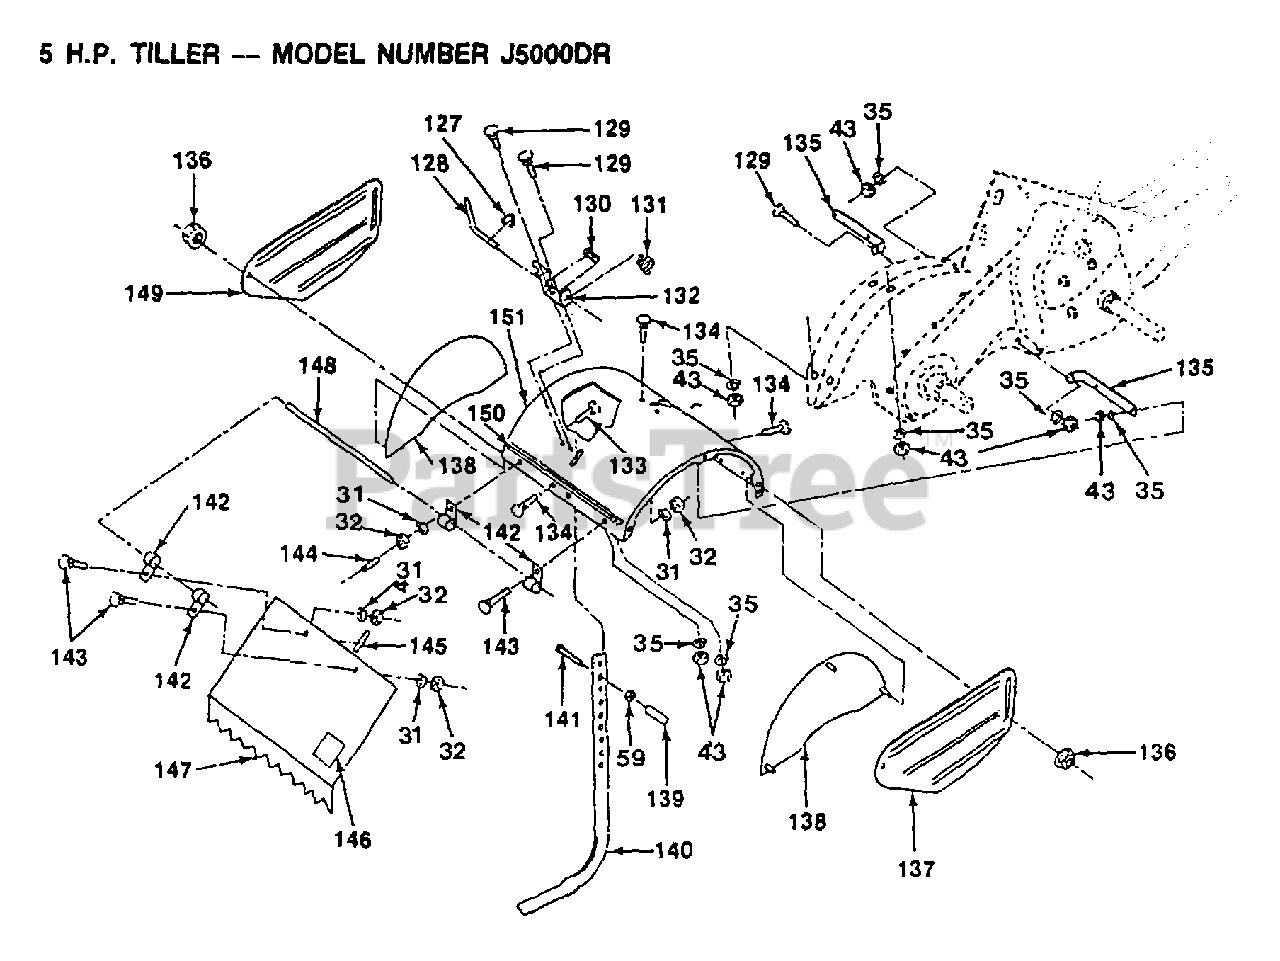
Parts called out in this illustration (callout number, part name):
127	STAKE PIN TI
128	KLIP RING TI
129	BOLT CRT
130	SPRING TI
131	SPRING CRT
132	LATCH BRACKET TI
133	BOLT
134	BOLT
136	NUT
139	GRIP CRT
141	BOLT
142	HINGE CRT
143	BOLT
144	VINYL CAP TI
145	PAD IDLER TI
148	PIN HINGE
150	DECAL, TINE SHIELD
